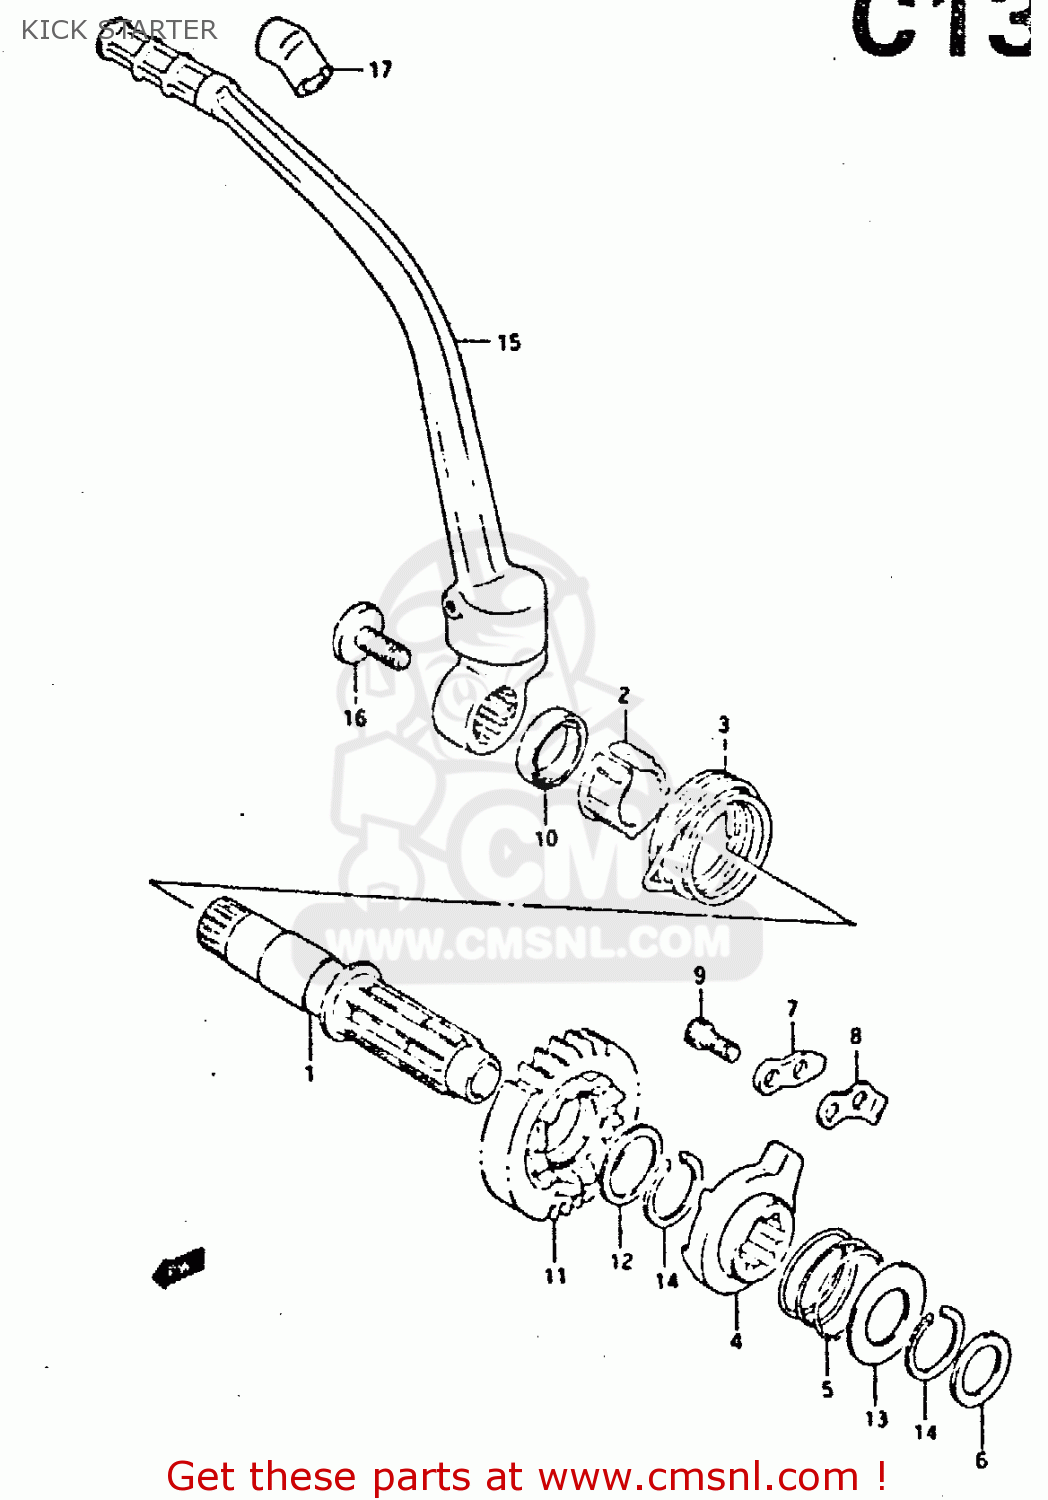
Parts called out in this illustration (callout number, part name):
1	SHAFT,KICK STARTER
2	GUIDE,KICK STARTER SFT SPRING
3	SPRING
4	STARTER,KICK
5	SPRING
6	WASHER,THRUST
7	GUIDE,KICK STARTER
8	STOPPER,KICK STARTER
9	BOLT,KICK START STOPPER
10	SEAL,OIL(20X27X6)
11	GEAR,KICK STARTER NO.2
12	SHIM
13	WASHER,THRUST
14	CIRCLIP
15	LEVER ASSEMBLY,KICK STARTER
16	BOLT(8X14)
17	COVER,KICK STARTER LEVER
